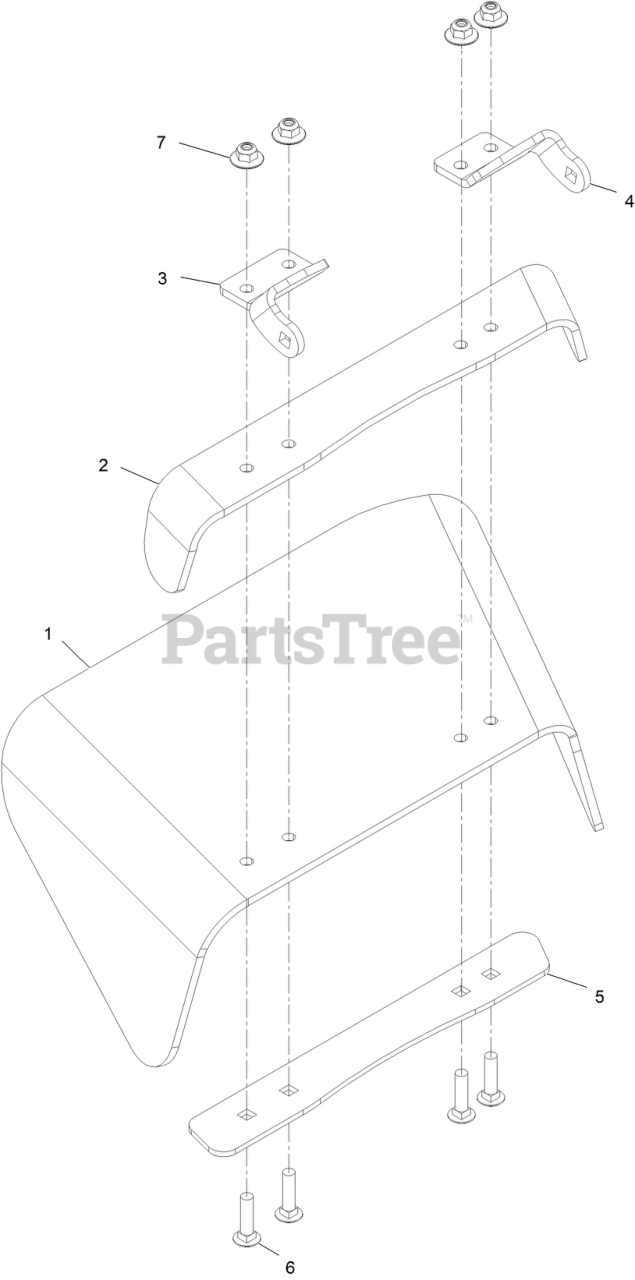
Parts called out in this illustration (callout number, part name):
1	DEFLECTOR-RUBBER
2	BRACKET-TOP DEFLECTOR
3	BRACKET-DEFLECTOR
4	BRACKET-DEFLECTOR
5	STRAP-BOTTOM DEFLECTOR
6	SCREW-CARR
7	NUT-FLANGE, NI
